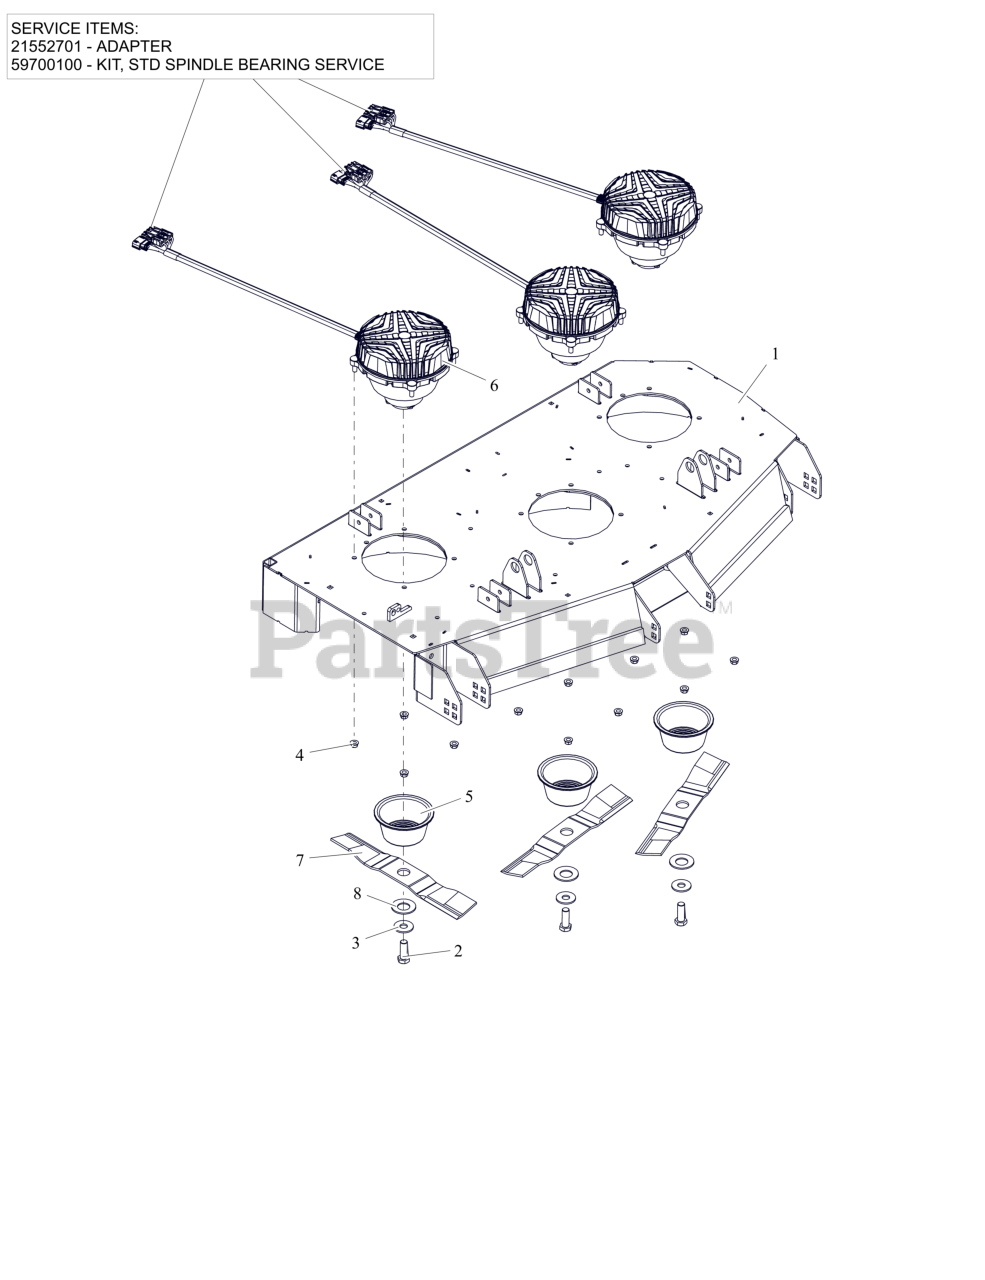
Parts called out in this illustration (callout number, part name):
1	KIT,DECK 48 SD W/DECALS-A
2	BLT, HEX .62-18X1.75 G8 ZCC
3	WSHR, HRDN 0.687X1.75X0.134 HRD
4	NUT-LK-CTR-FLG .375-16 GF ZCC
5	GUARD, SPINDLE LOWER
6	MOTOR, DECK - 48"/52" CW
6	ADAPTER
6	KIT,STD SPINDLE BEARING SERVICE
7	BLADE- MOWER-16.19" LOW
8	WSHR, BLVL - .56X28.5X3 PHOS.COAT
